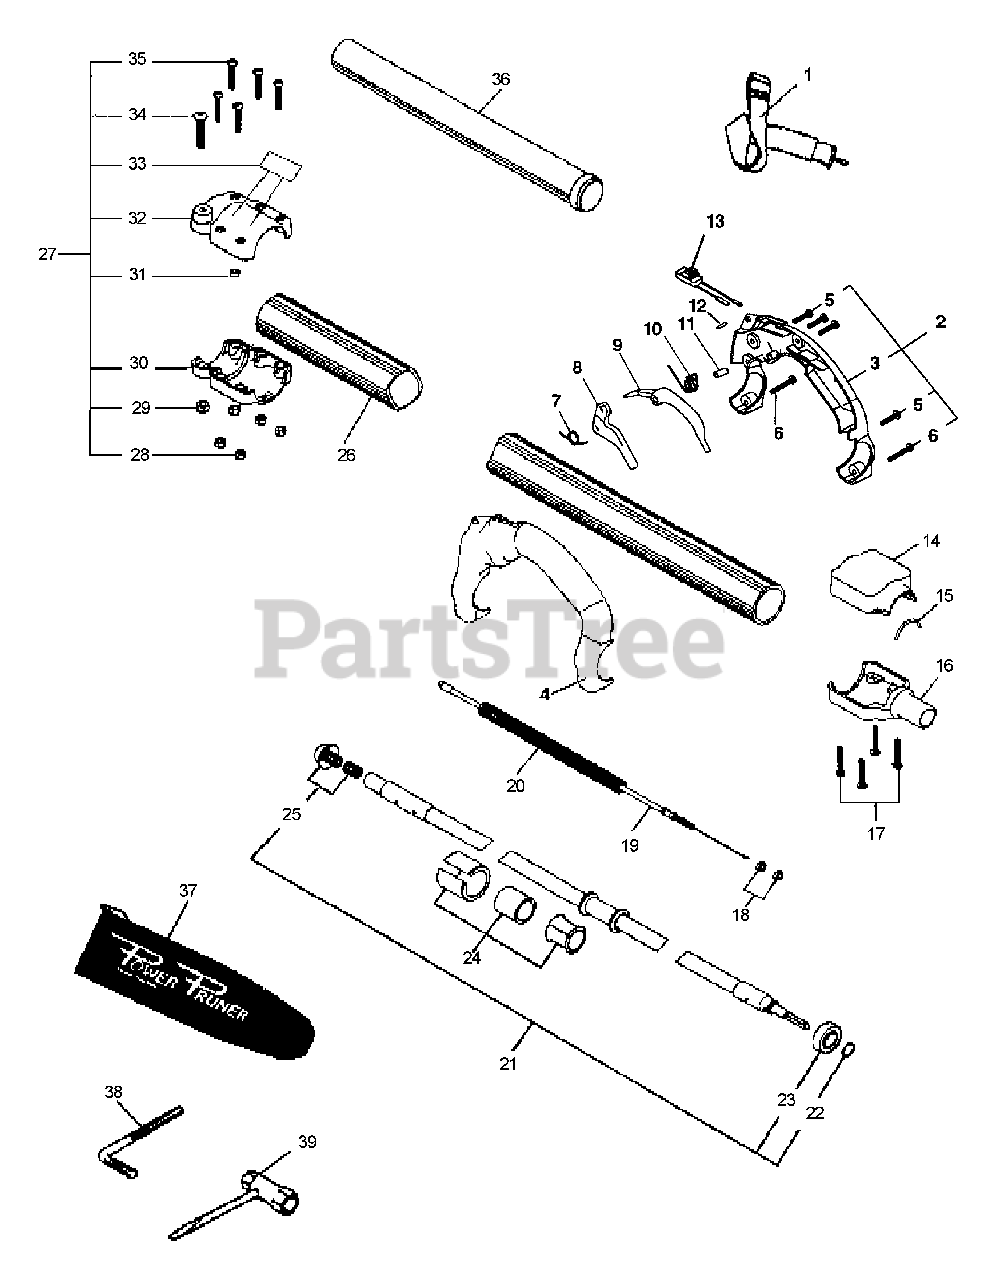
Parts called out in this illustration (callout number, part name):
1	SHOULDER STRAP ASSY
2	HANDLE ASSY - REAR
3	HANDLE, REAR - RIGHT
4	HANDLE, REAR - LEFT
5	SCREW - 10-24 X 1-1/4"
6	SCREW - 10-24 X 7/8"
7	SPRING, TRIGGER
8	TRIGGER, THROTTLE
9	LOCKOUT, THROTTLE
10	SPRING, LOCKOUT LEVER
11	COLLAR - 5
12	PIN - LOCATING
13	IGNITION SWITCH ASSY
14	LOWER HSNG ADAPT (TOP)
16	ADAPTER - LOWER
17	SCREW - 10-24 X 1-1/4"
19	CABLE, THROTTLE
20	TUBE, PROTECTIVE - CORRUGATED
21	DRIVESHAFT ASSY
22	RING, RETAINING
23	BEARING, BALL - 6002
24	DRIVESHAFT GUIDE ASSY
25	ADAPTER, DRIVESHAFT - UPPER
26	PIPE, MAIN
27	COLLAR ASSY
28	LOCKNUT - 10-24
30	COLLAR, MAIN PIPE - LOWER
32	COLLAR, MAIN PIPE - UPPER
33	LABEL - CAUTION
35	SCREW - 10-24 X 1-1/4"
36	PIPE, MAIN
37	COVER, GUIDE BAR
38	HEX KEY - 3mm
39	T-WRENCH
